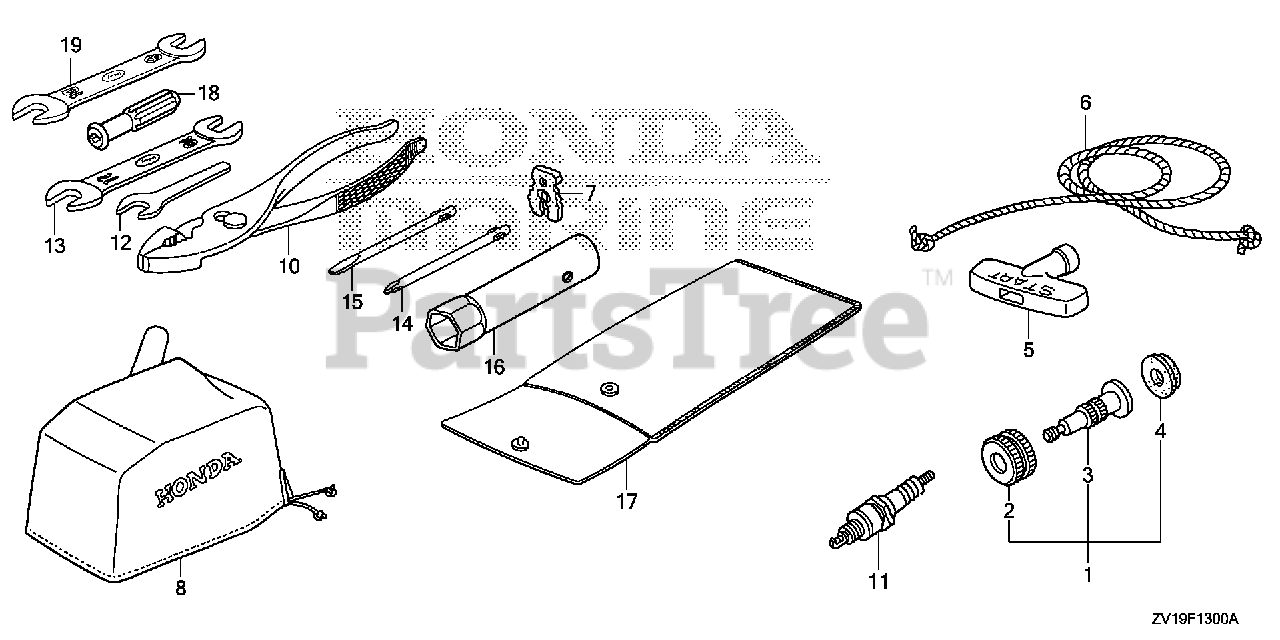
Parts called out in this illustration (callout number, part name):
2	NUT, WATER MOUTH Use from Frame SN 1000929.
3	JOINT, WATER HOSE
4	SEAT, WATER MOUTH Use from Frame SN 1000929.
5	GRIP, STARTER
6	ROPE, RECOIL STARTER (1300MM)
7	CLIP, EMERGENCY LOCK
8	COVER, BODY
10	PLIERS (135) (RIKEN)
11	SPARK PLUG (W16EPR-U)
11	SPARK PLUG (BPR5ES) (NGK)
12	WRENCH (8MM) (OPEN END)
13	WRENCH (10X12) (OPEN END)
14	SCREWDRIVER 1, PHILLIPS (NO.2)
15	SCREWDRIVER 3, STRAIGHT SLOT (NO. 2)
16	WRENCH, BOX (P21)
17	BAG, TOOL (160MM)
18	GRIP, SCREW DRIVER
19	SPANNER (8X10)
